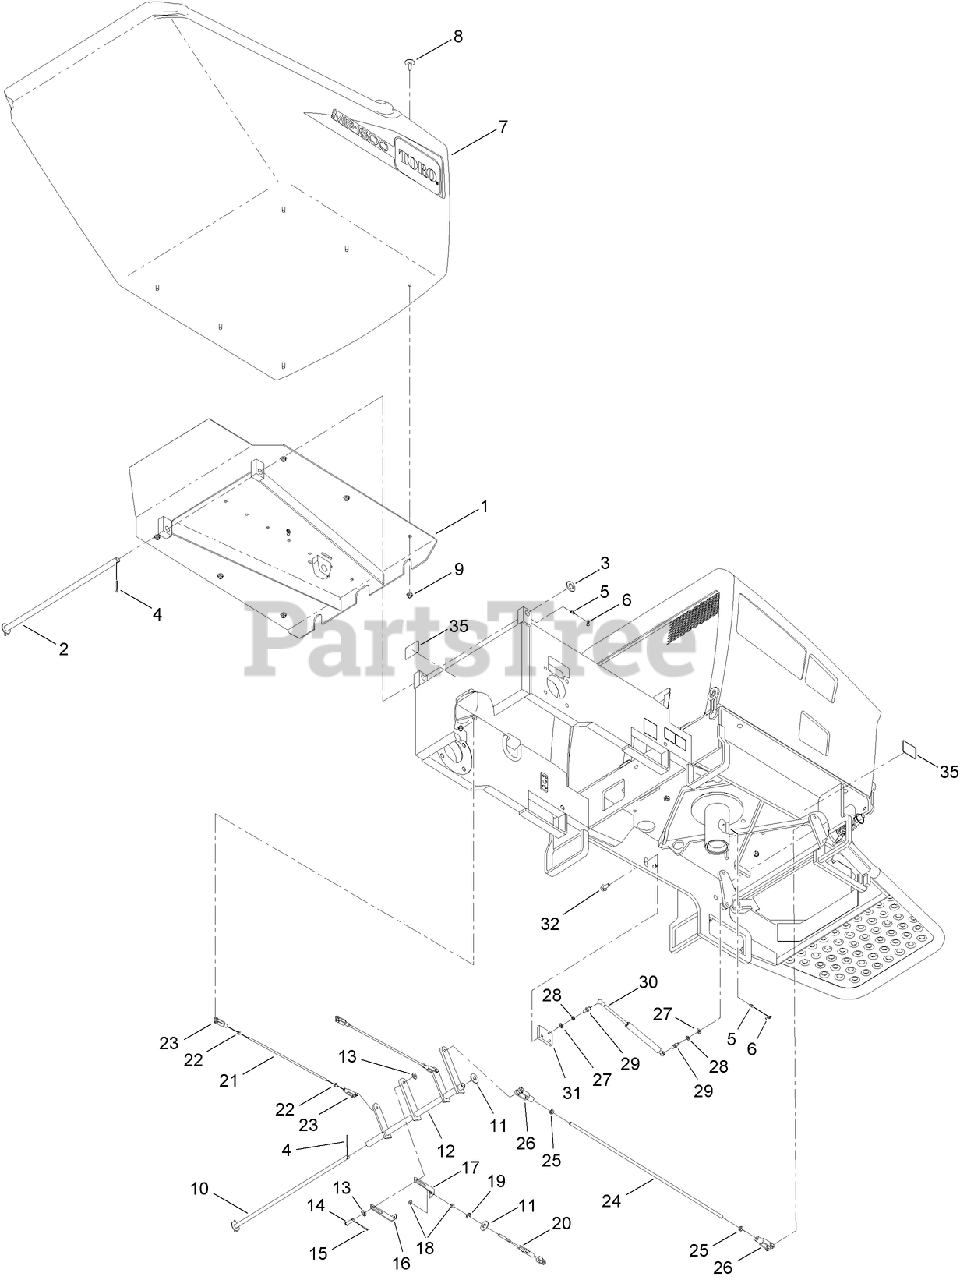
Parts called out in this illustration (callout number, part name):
1	BIN-BASE
2	SHAFT-PIVOT
3	WASHER-FLAT
4	PIN-COTTER
5	FITTING-GREASE
6	CAP-PLUG
7	HOPPER-MORTAR
8	BOLT-ELEVATOR
9	NUT-HF, NI
10	SHAFT-PIVOT, LEVER (BRAKE)
11	WASHER-FLAT
12	LEVER-BRAKE
13	WASHER-FLAT
14	PIN-CLEVIS
15	PIN-COTTER
16	CLEVIS-HALF
17	CLEVIS-HALF (NOTCHED)
18	NUT-JAM
19	RING-RETAINING, EXTERNAL
20	CABLE-BRAKE, BUGGY
21	ROD-BRAKE, FRONT
22	NUT-HEX
23	Clevis
24	ROD-BRAKE
25	NUT-HJ
26	END-YOKE
27	WASHER-PLAIN
28	WASHER-LOCK
29	STUD-BALL
30	SPRING-GAS
31	PLATE-PIVOT, SPRING (GAS)
32	SCREW-HHF
35	DECAL-TIE DOWN
